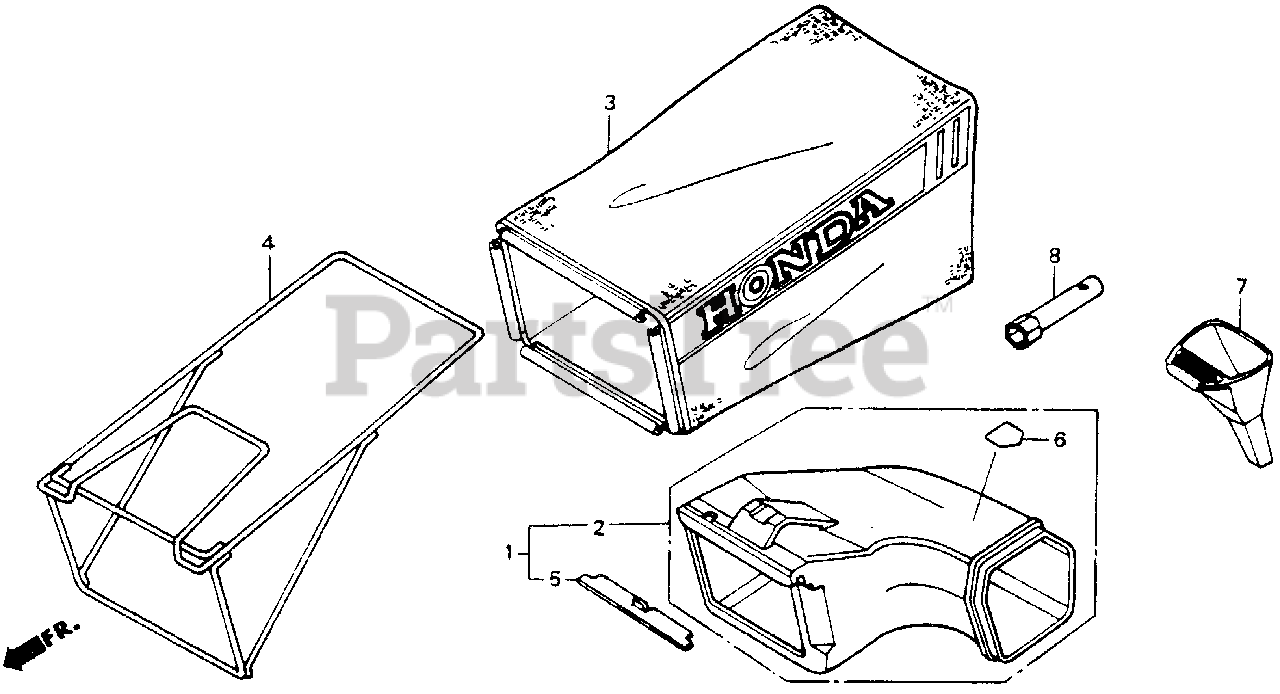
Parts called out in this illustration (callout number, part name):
2	CHUTE KIT, SIDE DISCHARGE
3	FABRIC, GRASS BAG
4	FRAME, BAG
6	LABEL B, HOUSING CAUTION (ENGLISH)
7	FUNNEL, OIL
8	WRENCH, BOX (P21)
